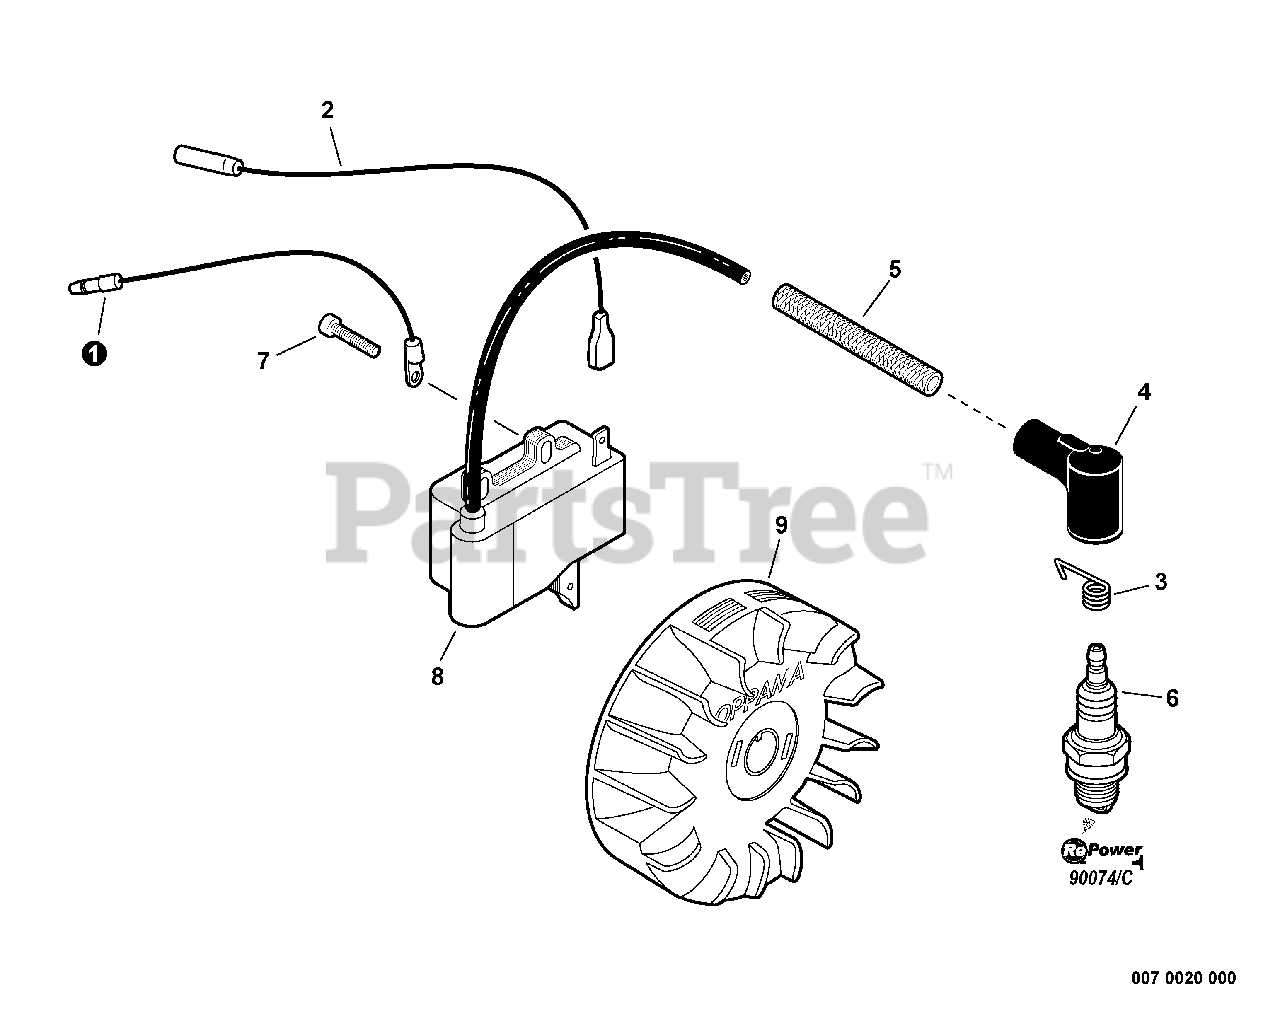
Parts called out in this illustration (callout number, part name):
1	LEAD - GROUND
2	LEAD - IGNITION
3	TERMINAL, SPARK PLUG CAP
4	CAP, SPARK PLUG
5	TUBE, INSULATOR
6	SPARK PLUG -- BPMR-8Y
6	SPARK PLUG -- BPM-8Y
7	SCREW - 4X20
8	COIL, IGNITION
9	FLYWHEEL
10	RePower TUNE-UP KIT
